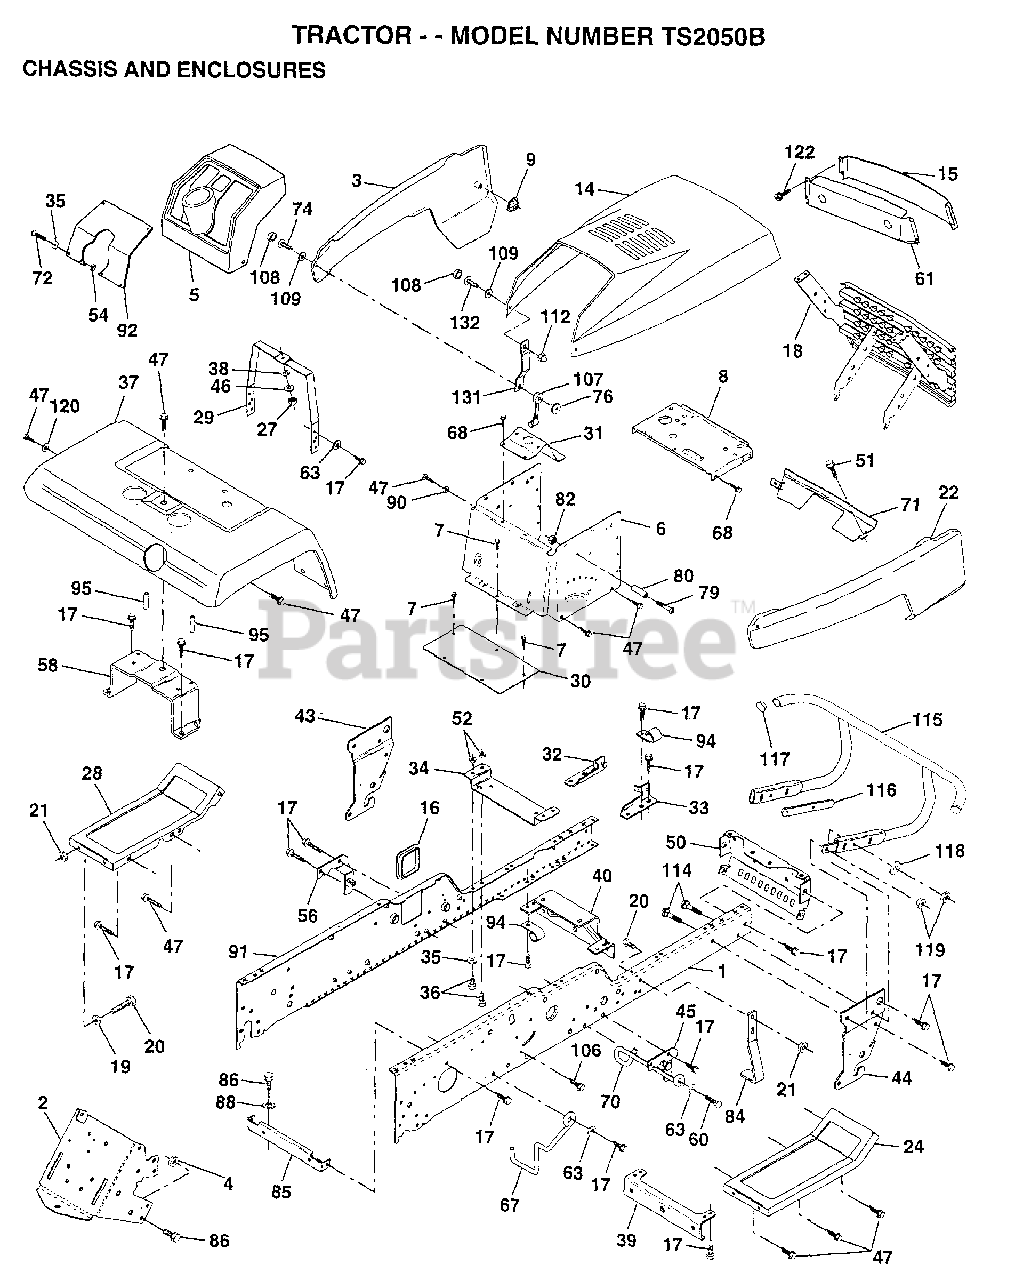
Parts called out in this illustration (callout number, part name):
1	"RAIL,FRAME RH"
2	DRAWBAR GT
3	PANEL ASM SIDE LH
4	NUT.7/16
5	DASHBOARD BLACK
6	"DASH AS.,LOWER"
7	SCREW
8	SUPPORT.DASH.BTRY
9	PAL NUT LT
15	LENS.BAR.CLEAR
16	COVER ACCESS
17	SCREW
19	WASHER
20	BOLT
24	FOOTREST.RH.LT/GT
28	FOOTREST.LH.LT/GT
29	DASH.SUPT.YP/HUSQ
30	SADDLE SLKSCR VGT
31	BRAKET.SUPT.STEER
32	BRACKET ASM FRAME
33	BRACKET ASM FRAME
34	BRACKET.ENG.SUPT.
35	WASHER
36	BOLT
37	FENDER
38	LOCKWASHER
39	BRACKET.AXLE.FRT.
43	BRACKET.SUS.FT.LH
44	BRACKET.SUS.FT.RH
46	WASHER PM
47	SCREW LT
50	"BRKT CHASSIS,FRNT"
51	SCREW CRT
58	BRKT.ASM.FENDER
60	SCREW
61	BEZEL.ASM.
63	WASHER
67	GUIDE BELT TRANS
68	SCREW LT
70	GUIDE.BELT.MID.SP
71	STRAP.GRILLE.PNT.
72	SCREW
74	SCREW
76	WELDNUT
79	SCREW
80	SPACER LT
84	STOP.OVER.CENTER
85	BRACKET.SUPT.TRAN
86	BOLT
88	LOCKWASHER
90	LOCKWASHER
91	"RAIL,FRAME LH"
92	PLATE YP SLKSCR
94	CLIP GTV
95	NUT-PUSH YT
107	HOOD LATCH T
108	SNAP CAP LT
109	WASHER LT
112	ACORN NUT RB
114	BOLT.3/8-14X1.25
115	BUMPER.ASM
116	BRACKET.EXT.BUMP.
117	PLUG.PLASTIC
118	WASHER
120	WASHER HYT
131	BKT.SPT.HOOD/PANL
132	SCREW.10-24X3/8.
